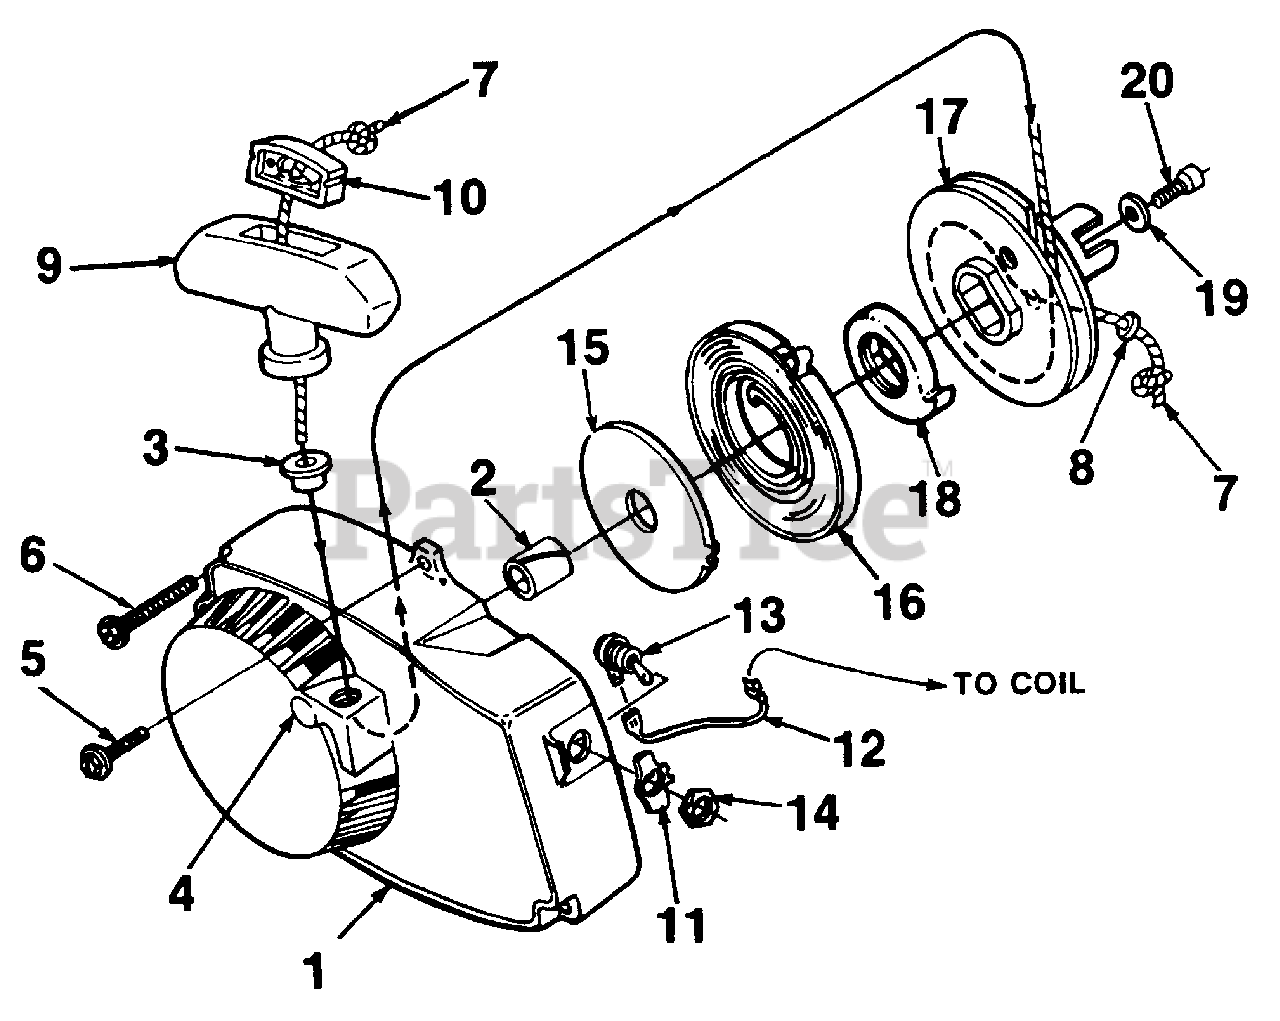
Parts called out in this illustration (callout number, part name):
1	HOUSING- Fan
2	BUSHING- Starter
3	BUSHING- Rope
4	DRIVE- Stud
5	SCREW- Hex 12-24 x 9/16
6	SCREW- Hex 12-24 x 1 1/16
7	ROPE- Starter 48" long #5
8	WASHER- Flat (nylon)
9	GRIP- Starter rope
11	PLATE-"On-Off"
12	LEAD- Ground (solid state)
13	SWITCH & LEAD
14	NUT
15	SHIELD- Spring (inner)
16	SPRING- Recoil
17	PULLEY- Starter
18	BUSHING- Spring
19	WASHER- Retainer
20	SCREW- Hex 10-32 x 1/2
